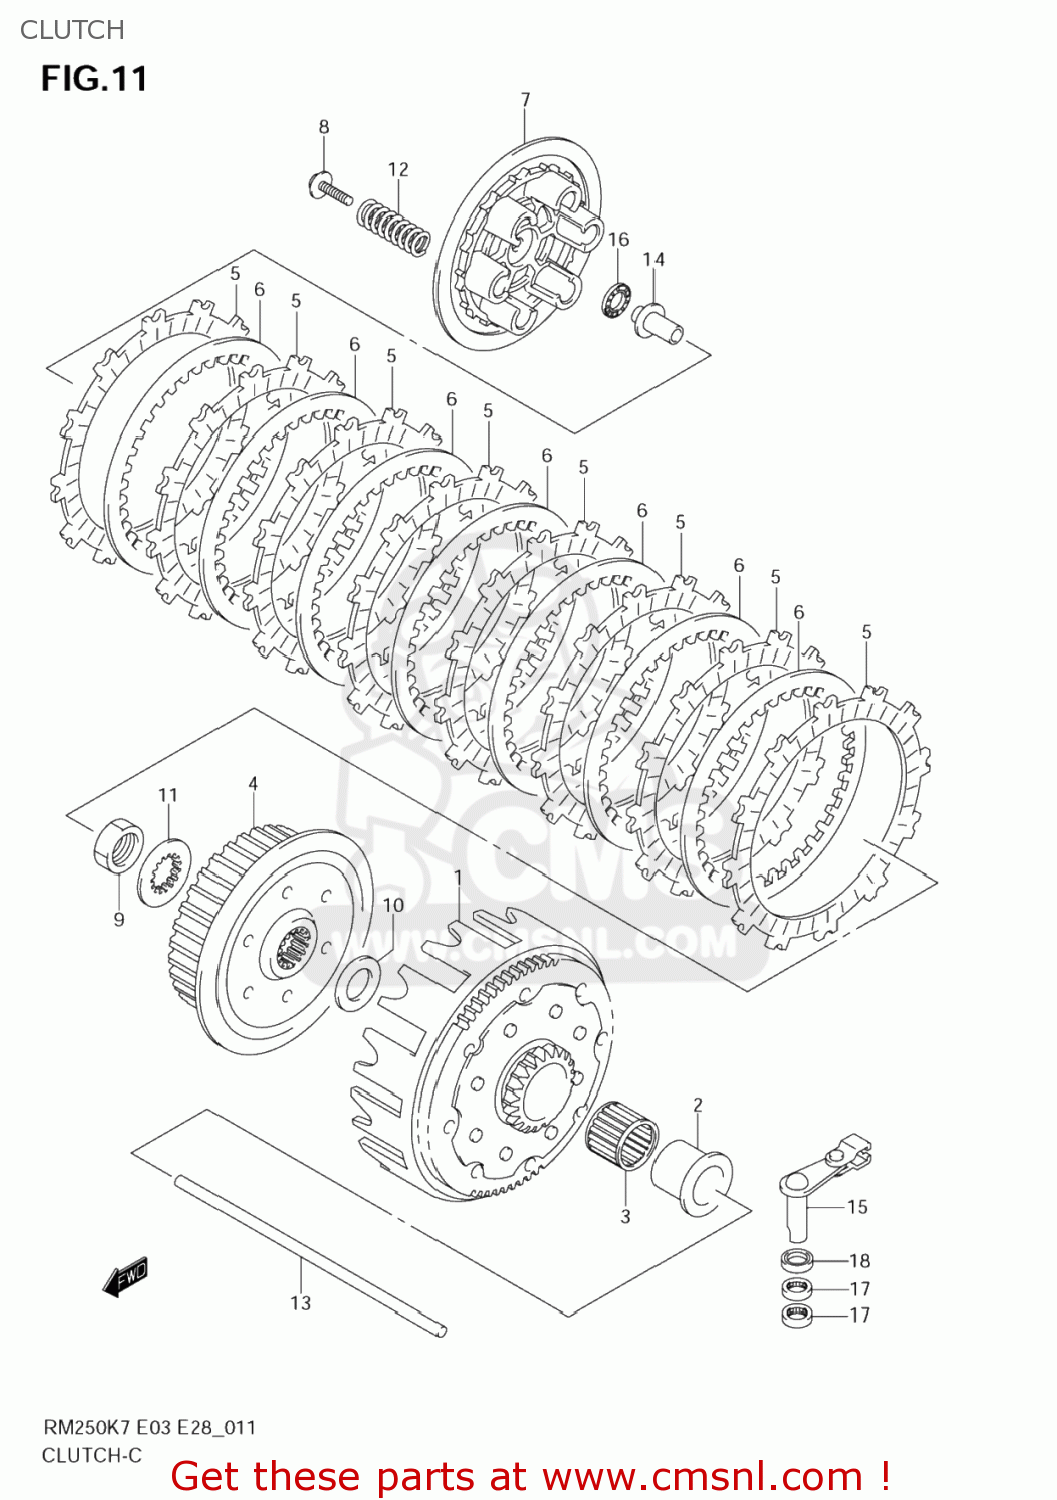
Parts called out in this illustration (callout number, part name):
1	GEAR ASSY,PRI DRIVEN
2	SPACER,PRIMARY DRIVEN GEAR
3	BEARING(29X34X27)
4	HUB,CLUTCH SLEEVE
5	PLATE,CLUTCH DRIVE (NAS)
6	PLATE,CLUTCH DRIVEN (NAS)
7	DISC,CLUTCH PRESSURE
8	BOLT(5X25)
9	NUT
10	WASHER(22.5X39X3)
11	WASHER,LOCK
12	SPRING
13	ROD,CLUTCH PUSH
14	PIECE,CLUTCH PUSH
15	CAMSHAFT,CLUTCH RELEASE
16	BEARING(10X22X2.8)
17	BEARING(12X16X10)
18	SEAL,OIL(12X19X5)
